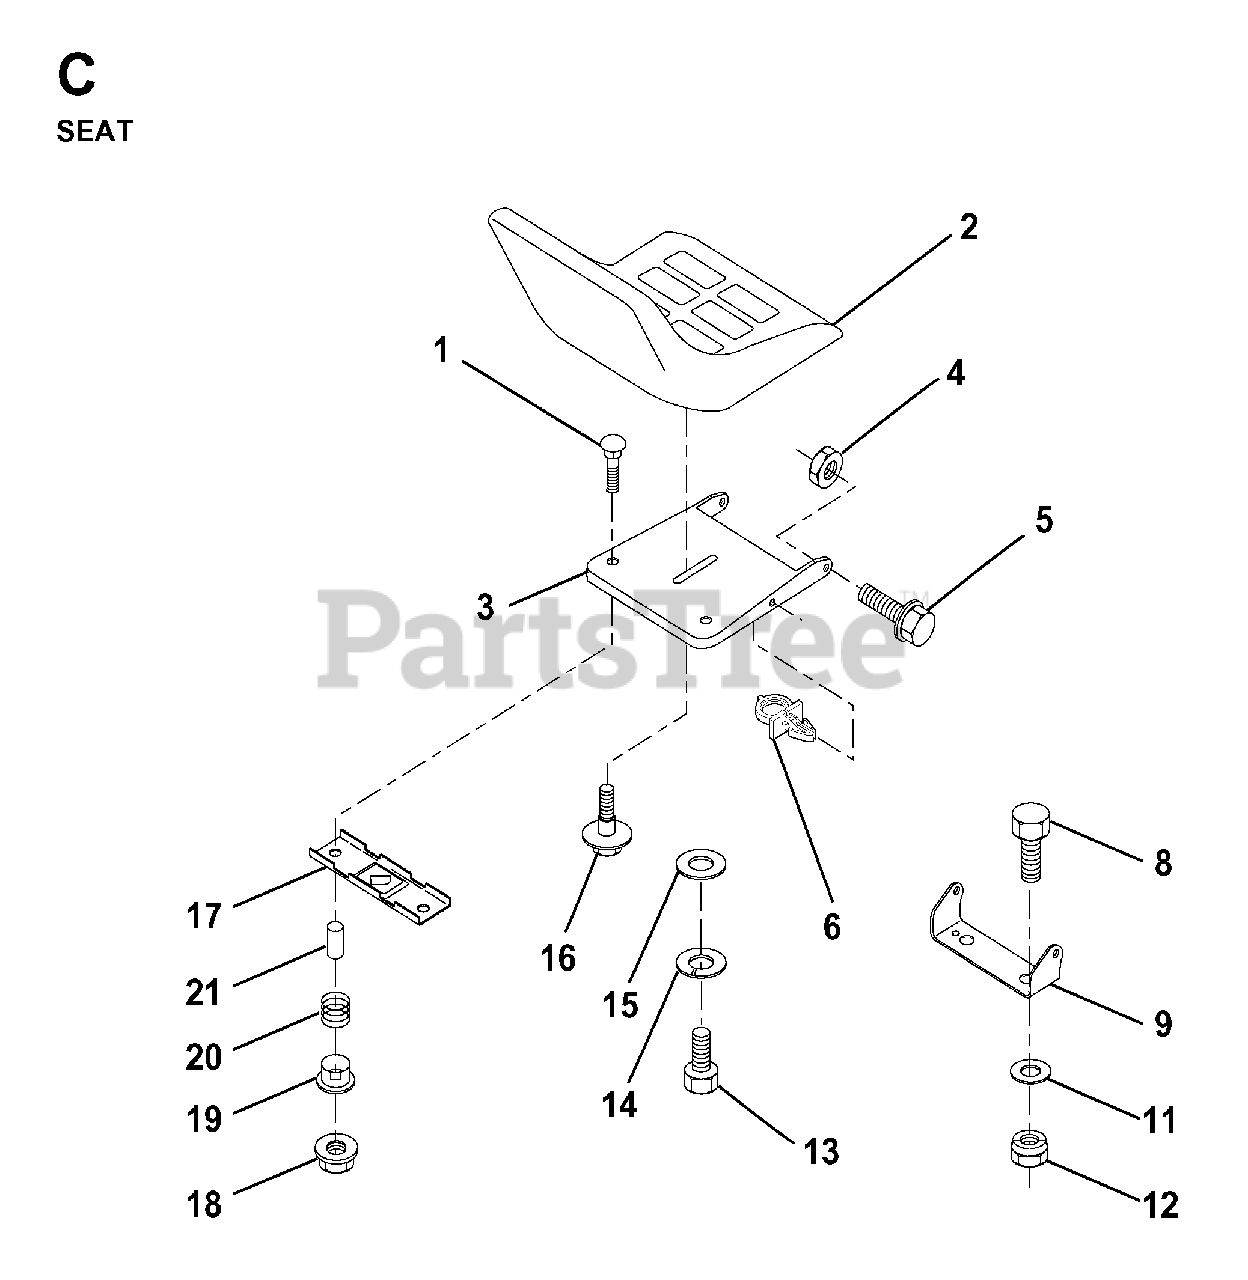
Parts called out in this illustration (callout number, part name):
1	BOLT.ROUND.HEAD.SQUARE.NECK
2	SEAT
3	PAN, SEAT
4	NUT.71038.31-18.HEX.NYLOCK
5	BOLT SHOULDER 5/16-18
6	PUSH CLIP
8	BOLT
9	SEAT PIVOT BRKT
11	WASHER 12/32X2X10GA
12	NUT
13	BOLT
14	LOCKWASHER
16	BOLT,SHOULD
17	BRKT SWITCH
18	NUT T
21	SPACER SPLIT 28X.96
